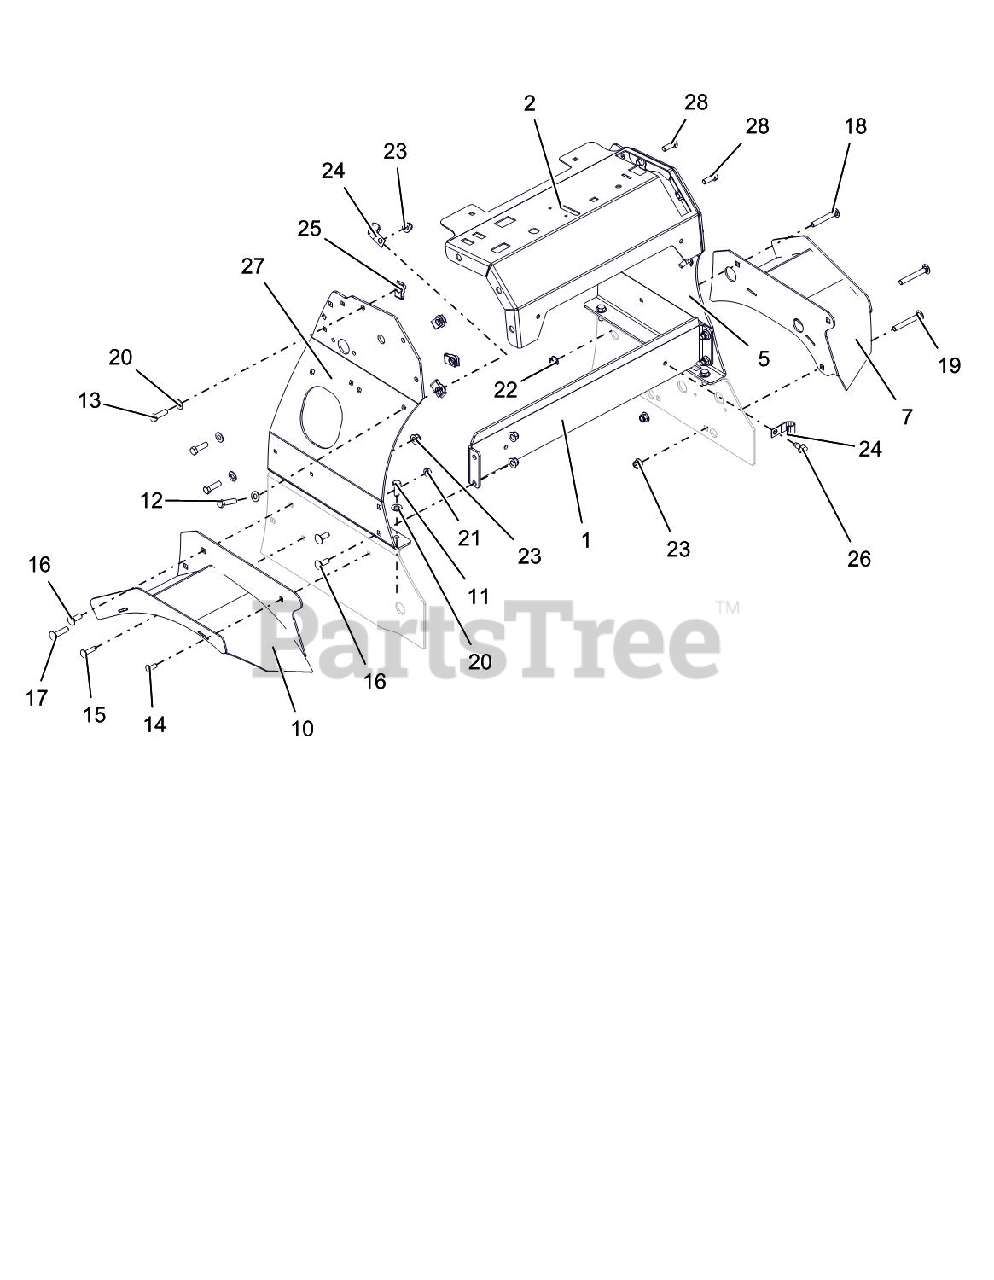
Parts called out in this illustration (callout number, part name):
1	STIFFENER, TOWER
2	KIT, 48-60 PS DASH WITH DECAL
5	PANEL, LH TOWER SIDE
7	WLDMT, LH FENDER
10	WLDMT, RH FENDER
11	@BLT-HEX .38-16X1.00 GR5 YWZC
12	@BLT-HEX .38-16X1.50 GR5 YWZC
13	@BLT-HEX .38-16X1.25 GR5 YWZC
14	@BLT-RDHDSQNK .31-18X.75 G5YZ
15	@BLT-RDHDSQNK .31-18X1.25 G5YZ
16	@BLT-RDHDSQNK .38-16X1.00 G5YZ
17	@BLT-RDHDSQNK .38-16X1.50 G5YZ
18	@BLT-RDHDSQNK .38-16X2.50 G5YZ
19	@BLT-RDHDSQNK .38-16X2.75 G5YZ
20	@WSHR-FL-STL.406X.812X.065 YWZ
21	@NUT-SPNLK-FLG .312-18 YWZC
22	@NUT-LK-TOP-FLG .38-16 YWZC
23	@NUT-LK-NYL-FLG .38-16 YWZC
25	NUT-RTNR .375-16X.37
26	@SCR-TAP .38-16X.75 HWH TR YWZ
27	KIT, SERVICE RH TOWER
28	@BLT-HEX .38-16X1.00 GR5 YWZC
